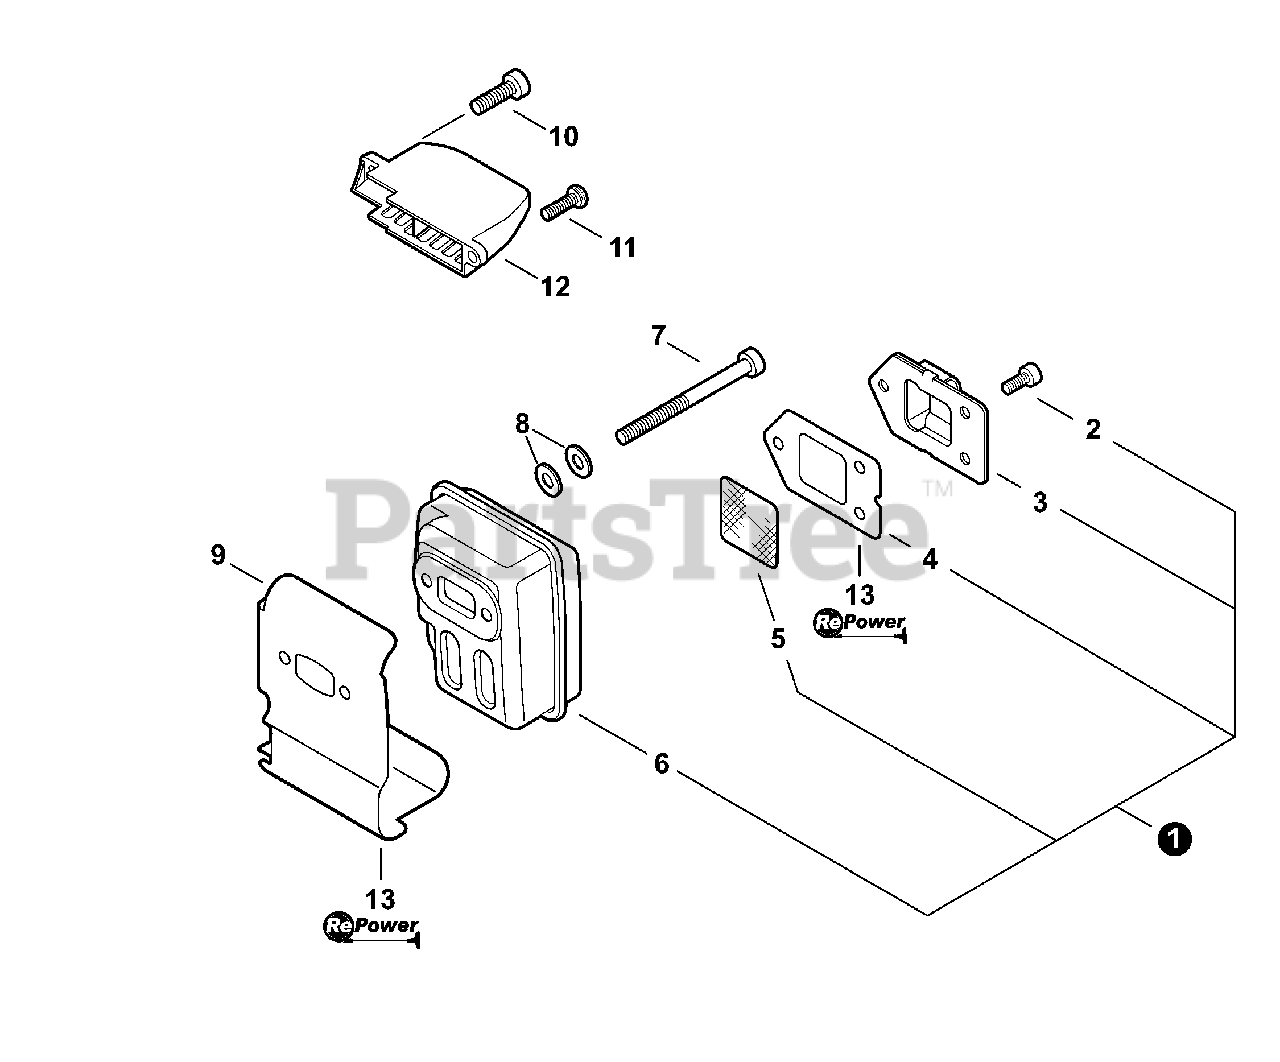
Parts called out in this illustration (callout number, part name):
1	MUFFLER ASSY
2	BOLT, TORX 4×8
3	GUIDE, EXHAUST
4	GASKET, EXHAUST
5	SCREEN, SPARK ARRESTER
7	BOLT, TORX 5×55
8	WASHER, FLAT 5.5×10×0.8
9	HEAT SHIELD, EXHAUST
10	BOLT, TORX 5×16
11	BOLT, TORX 5×16
12	COVER, MUFFLER
13	GASKET KIT
